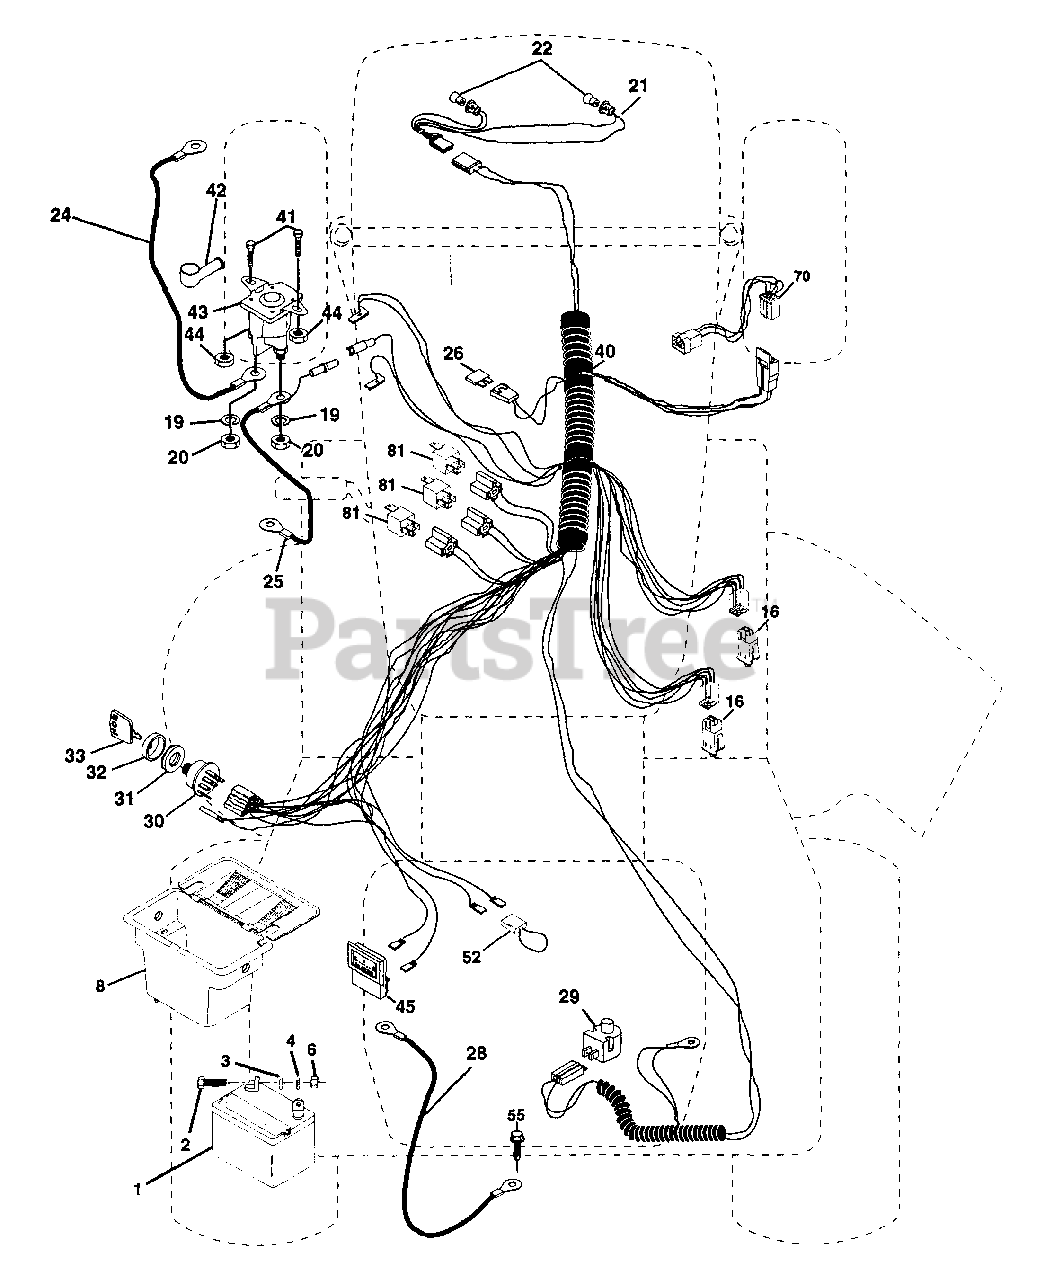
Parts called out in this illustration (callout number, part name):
1	Battery 12 Volt 28 Amp
2	Bolt Hex Hd 1/4-20unc X 3/4
3	Washer 9/32 X 5/8 X 16 Ga
4	Washer Lock Hvy Helical 1/4
6	Nut Fin Hex 1/4-20 Unc
8	Case Battery
16	Switch Interlock N. Opn./N Opn.
19	Washer Lock 1/4
20	Nut Jam Hex 1/4-20 Unc
21	Harness Asm Light W/4152J
22	Bulb Light #1156
24	Cable Battery 6 Ga 11" red
25	Cable Battery 6 Ga w/16 wire, red
26	Fuse 30 AMP Auto Green
28	Cable Ground
29	Switch Plunger Normal Op. Olive
30	Switch Ign 3
31	Nut Ignition
32	Cover Sw Ignition
33	Key Ign
40	Harness Ign
41	Bolt Blk Fin Hex 1/4-20unc X 1/2
42	Cover Terminal Red
43	Solenoid
44	Nut Keps Blk Hex 1/4-20 unc
45	Ammeter
52	Protection Wire Loop (Hourmeter)
70	Harness Eng
81	Relay Asm.
